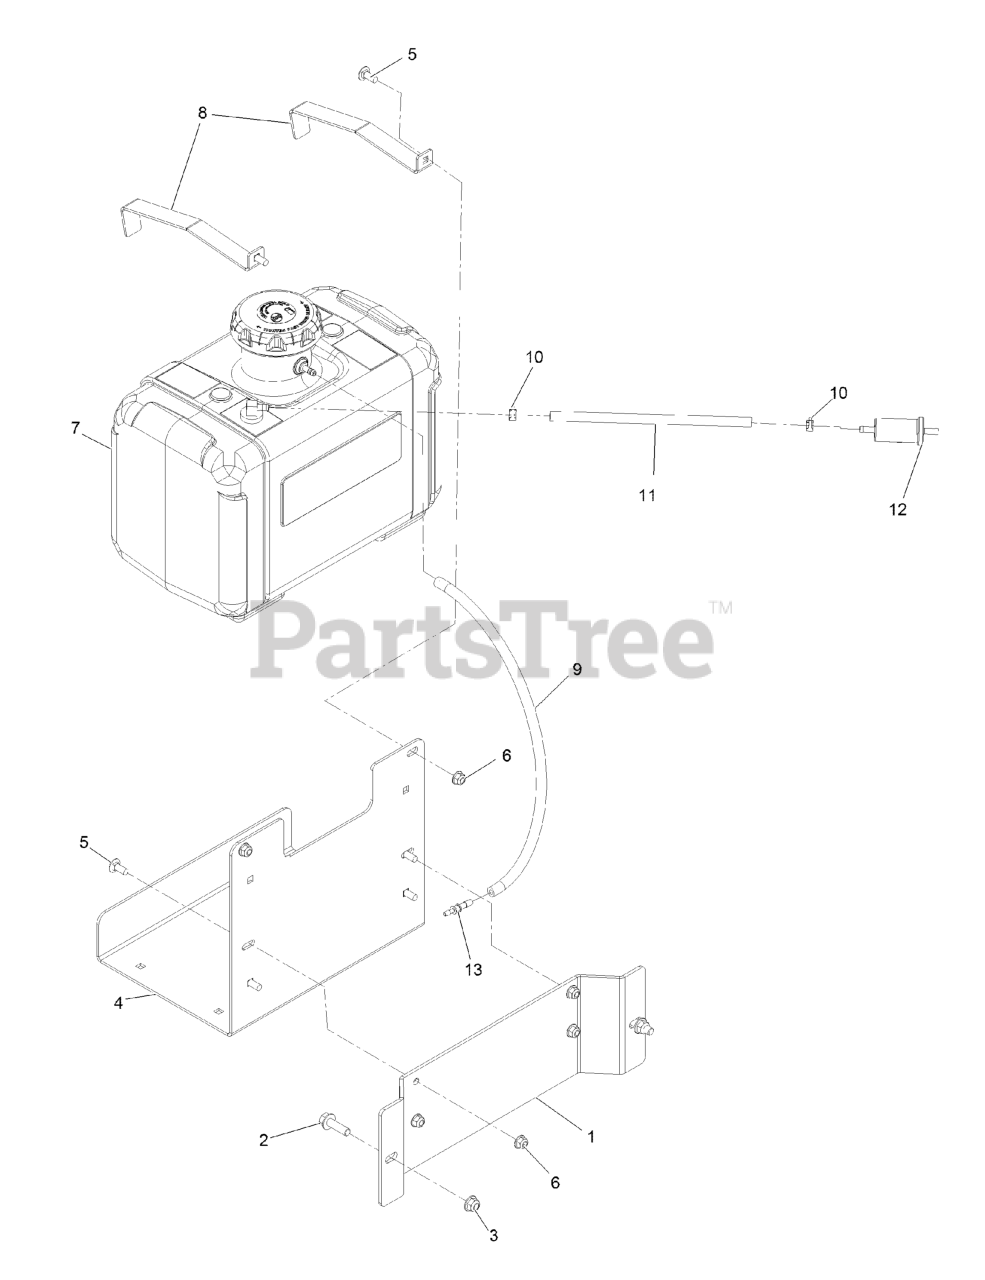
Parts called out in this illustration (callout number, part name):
1	MOUNT, GAS TANK, AE
2	SCREW-HHF
3	NUT-HF, NI
4	Mount-Tank,Bracket
5	SCREW-CARR
6	NUT-HF, NI
7	ASM-Tank, 5 Gal.
8	Strap-Tank, Ae
9	HOSE-FUEL
10	CLAMP-HOSE
11	HOSE-FUEL
12	FILTER-FUEL
13	BARB-FUEL
